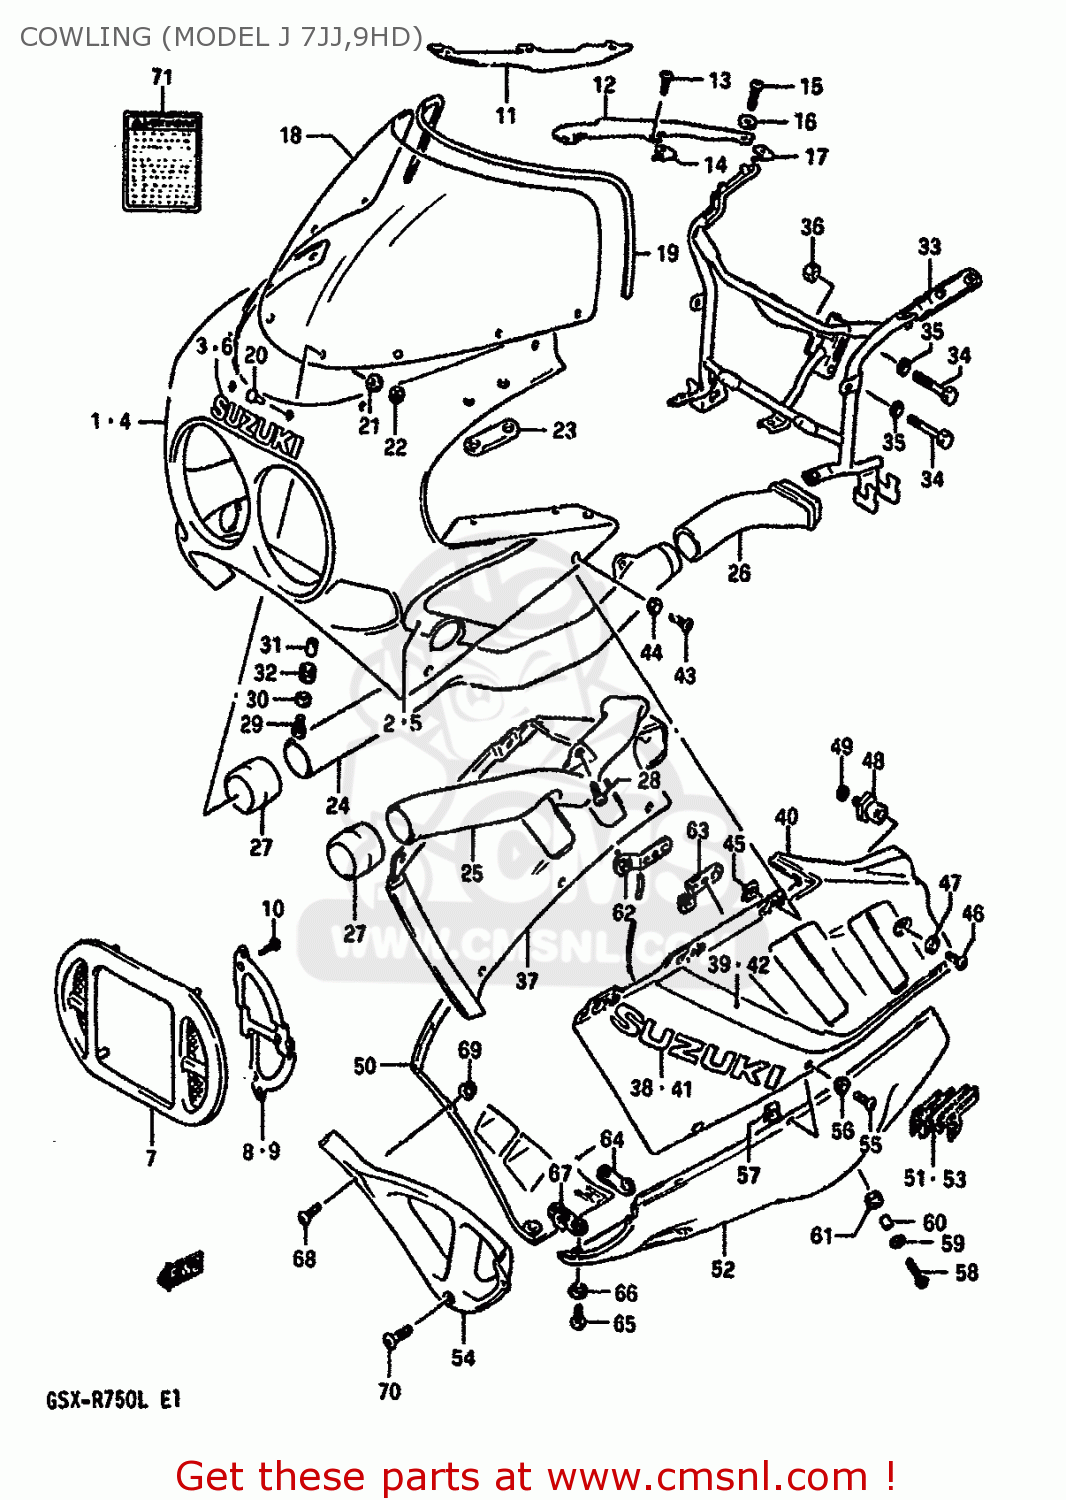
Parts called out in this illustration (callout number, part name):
1	BODY ASSEMBLY,COWLING
2	TAPE SET
3	EMBLEM,LEG SHIELD
4	BODY ASSY,COWLING (WHITE/RED)
5	TAPE SET
6	EMBLEM,LEG SHIELD
7	COVER,FRONT (RED)
8	PLATE,COVER RH
9	PLATE,COVER LH
10	TAPPING SCREW 4X10/A
11	PANEL,COWLING UPPER,RIGHT
12	COVER,COWLING,LEFT
13	SCREW(5X10)
14	NUT
15	SCREW(5X14)
16	WASHER(5.2X11X1)
17	NUT
18	WINDSCREEN
19	MOLDING
20	PIN,WINDSCREEN
21	CUSHION
22	NUT
23	CUSHION,RR VIEW MIRRORR
24	PIPE,AIR INTAKE,FRONT
25	PIPE,AIR INTAKE,FRONT
26	PIPE,AIR INTAKE RR,R
27	JOINT,AIR INTAKE
28	SCREW
29	SCREW(6X20)
30	WASHER(6.5X18X1)
31	SPACER
32	CUSHION
33	BRACE,COWLING
34	BOLT
35	WASHER,LOCK,8.
36	NUT ,8MM
37	COVER,SIDE RH (BLACK/RED)
38	EMBLEM,COVER S
39	TAPE,RH
40	COVER,SIDE LH (BLACK/RED)
41	EMBLEM,COVER S
42	TAPE,LH
43	SCREW(5X18)
44	WASHER(5.2X14X1.5)
45	NUT,HEADLAMP HOUSING,UPPER
46	SCREW(6X12)
47	WASHER(6.3X16X1.5)
48	CUSHION,COWLING
49	WASHER,LOCK
50	COWLING,UNDER
51	EMBLEM
52	COWLING,UNDER LH (WHITE/RED)
53	EMBLEM
54	COWLING,UNDER,CENTER
55	SCREW(5X18)
56	WASHER(5.2X14X1.5)
57	NUT,HEADLAMP HOUSING,UPPER
58	SCREW(6X20)
59	WASHER(6.5X18X1)
60	SPACER
61	CUSHION
62	BRACKET
63	BRACE,COWLING UNDER,LH
64	BRACE,COWLING LWR COVER RR
65	SCREW(6X16)
66	WASHER(6.3X16X1.5)
67	BRACE,COWLING LWR COVER
68	SCREW(5X14)
69	NUT
70	SCREW(6X16)
71	LABEL (WARNING SCREEN)
